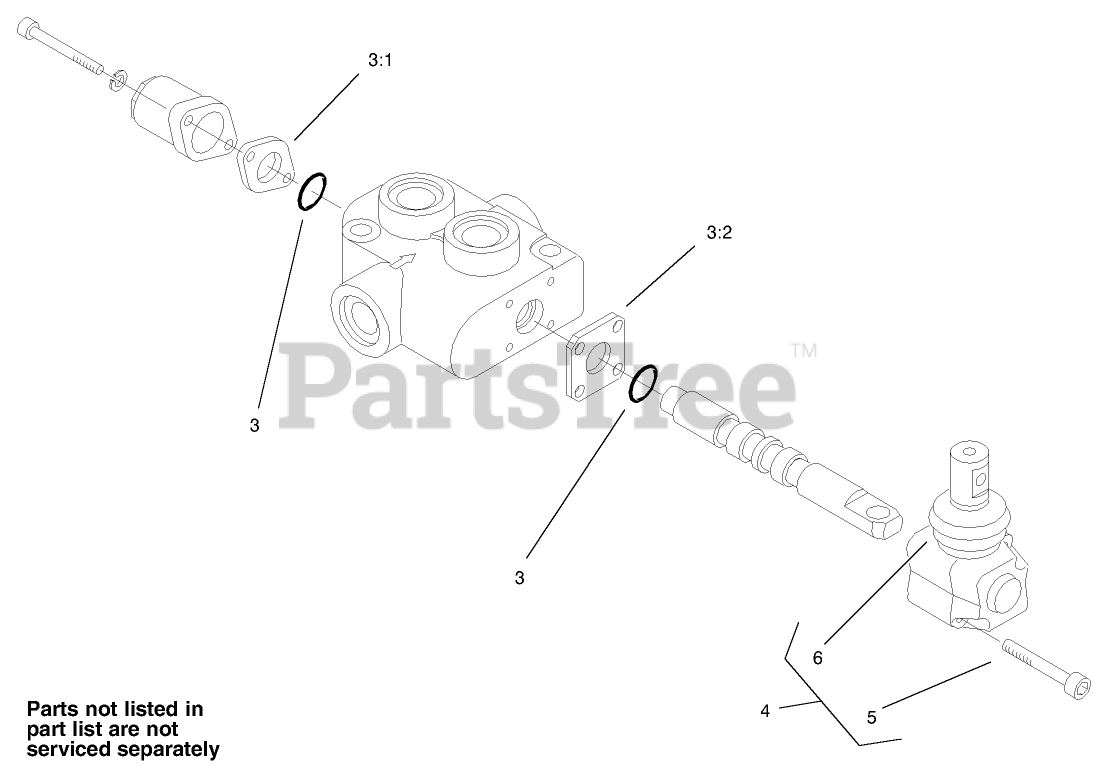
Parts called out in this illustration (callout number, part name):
3	SEAL KIT
3:1	GASKET
3:2	GASKET
